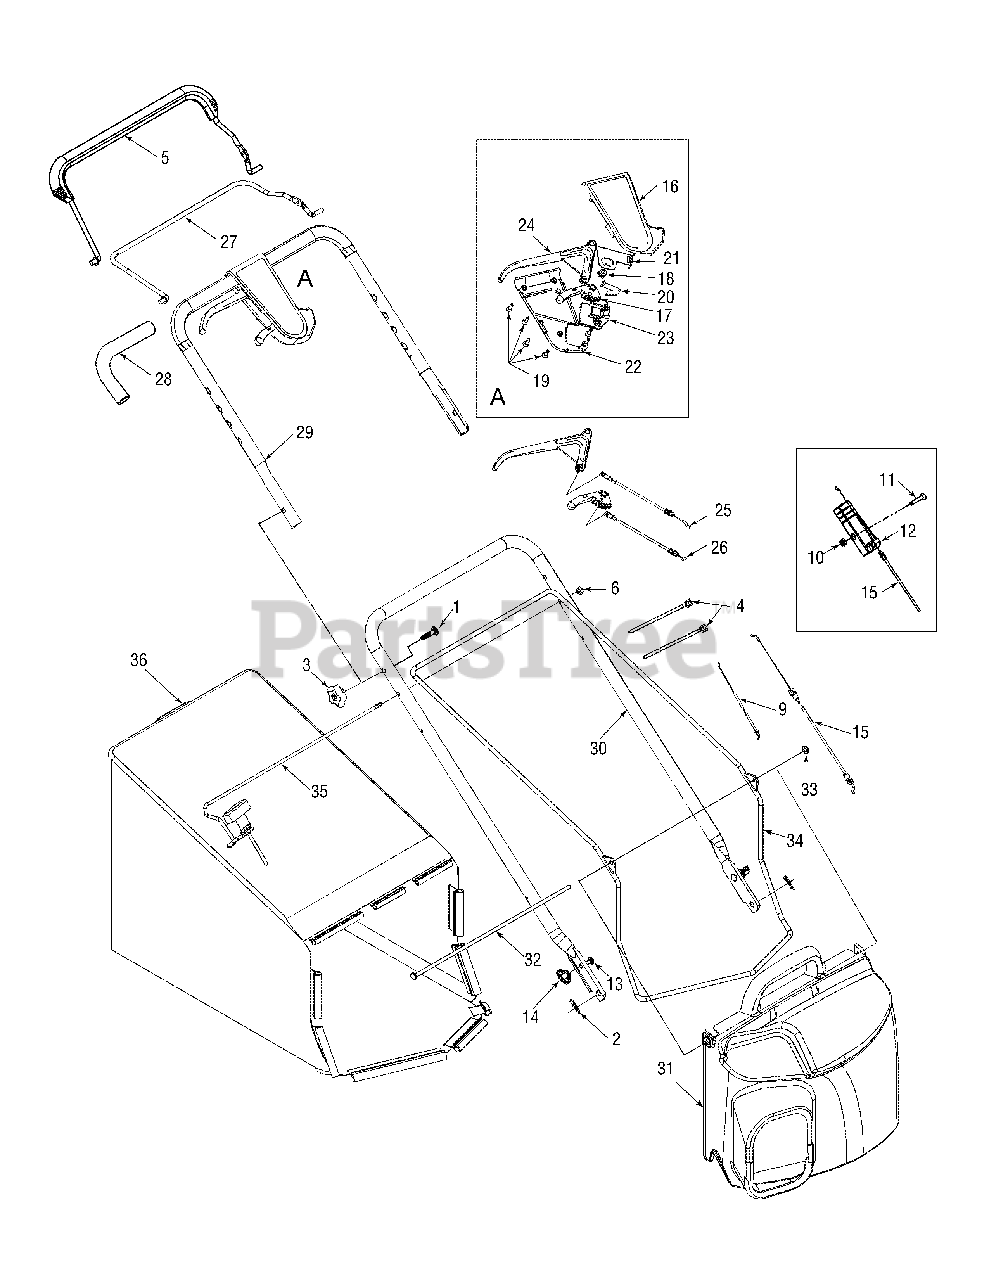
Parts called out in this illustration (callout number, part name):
1	Carriage Bolt 5/16-18 x 2.0
2	Int. Cotter Pin 5/16 DIA
4	Cable Tie
5	Control Bail Lever - Deluxe Black
6	Flg. Lock Nut 5/16-18 Gr. F Nylon
8	Cup. Wash. .265 ID x .75 OD x .062
9	Throttle Wire 60.0" Lg. Yellow
10	Hex Ins. Locknut 1/4-20
11	Mach. Scr. 1/4-20 x 1.319
12	Cable Bracket
13	Carriage Bolt 1/4-20 x .75
14	Wing Nut
15	Control Cable 47.0" Lg.(B&S)
16	Control Cover
17	6 Speed Shift Lever
18	3 Tooth Rack Gear Insert
19	C-sunk Tap Screw #10 x .75
20	Shift Lever Spring
21	Rack Cable Bracket
22	Control Cover
23	Control Cover
24	Control Lever
25	Pulley Cable 53" Lg.
26	Clutch Cable - 53" Lg. Orange
27	Control Bail Lever
28	Foam Grip
31	Grassbag Cover w/Label
32	Grasscatcher Pivot Rod
33	Push Cap
34	Grasscatcher Upper Frame
35	Grasscatcher Support Rod
